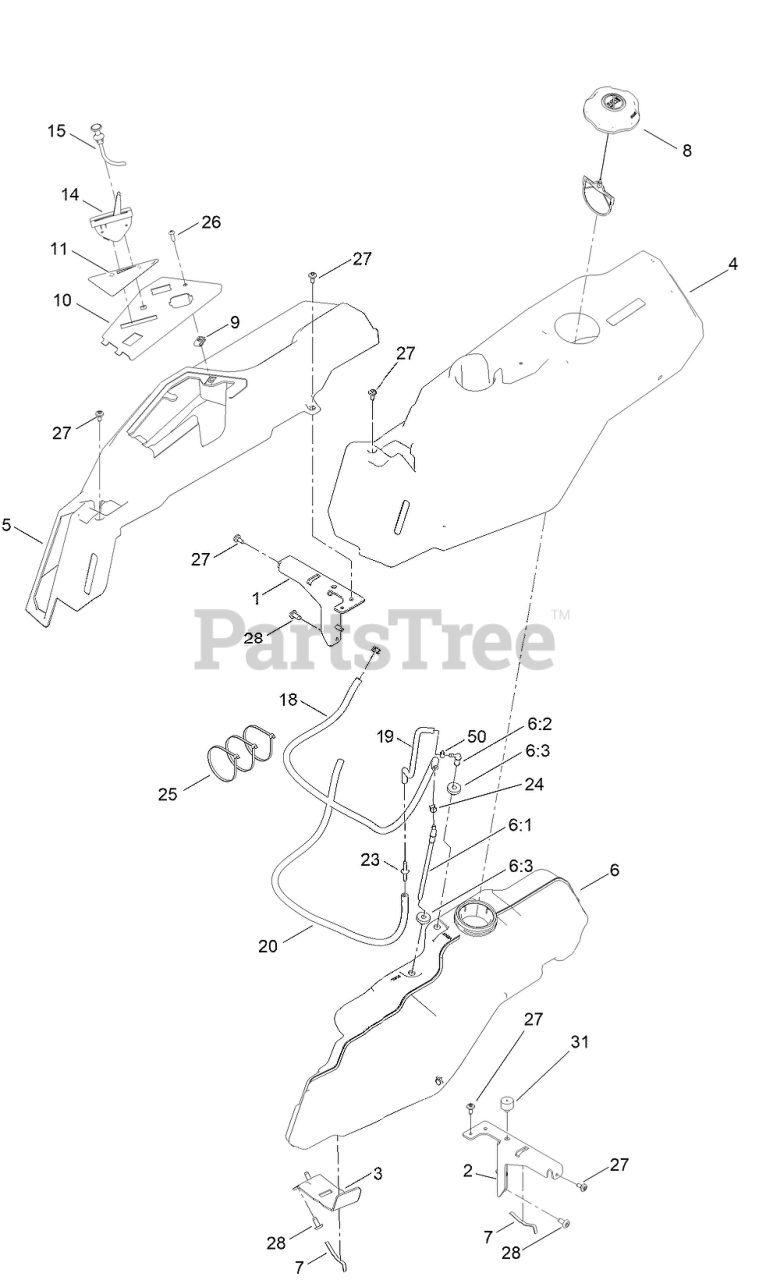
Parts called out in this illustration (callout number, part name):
1	BRACKET-POD
2	SUPPORT-POD, LH
3	SUPPORT-TANK, FUEL
4	POD-LH
5	POD-RH, MYRIDE
6	TANK-FUEL ASM
6:1	CONNECTOR-ELBOW, 90 DEG
6:2	FITTING-ELBOW 90
6:3	BUSHING
7	SPRING
8	CAP-FUEL, RATCHETING
10	PANEL - CONTROL
11	DECAL-PANEL, CONTROL
14	CABLE-THROTTLE
15	CABLE-CHOKE
18	HOSE-FUEL
19	HOSE-FUEL
20	HOSE-FUEL
23	ADAPTER ORIFICE
24	CLAMP-HOSE
25	TIE-CABLE
26	SCREW-PRH
27	SCREW-SHOULDER
31	BUMPER-GROMMET
50	CLAMP-HOSE
